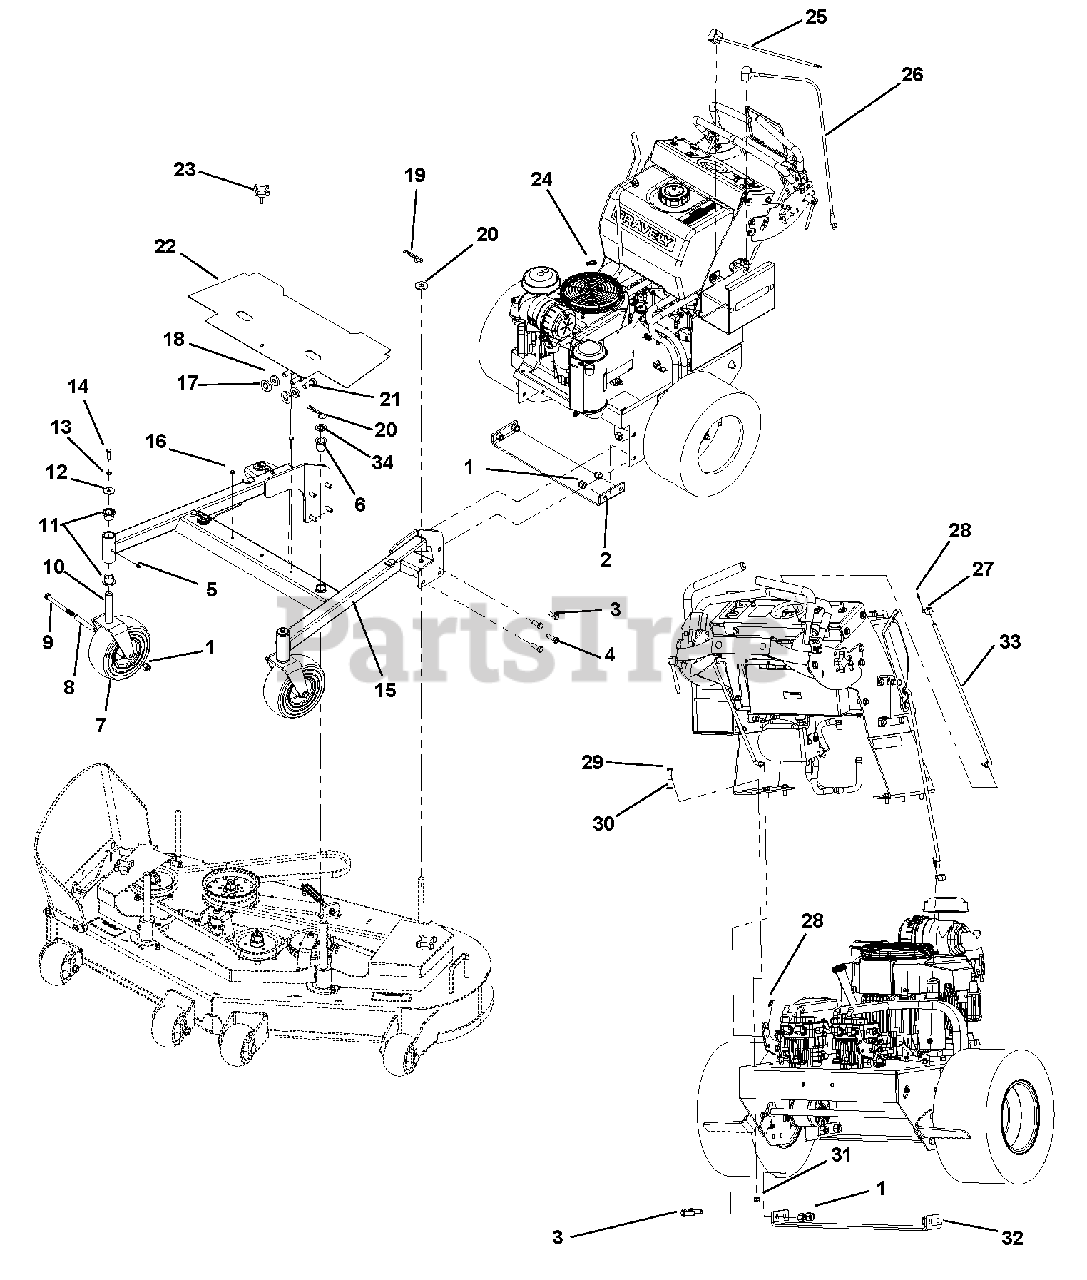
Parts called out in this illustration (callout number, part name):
1	LOCKNUT, 1/2-13 NYLOC Y
2	PLATE, ENGINE BED FRONT 48/52
3	BOLT, 1/2-13 X 1.25 HEX 5 Y
4	BOLT, 1/2-13 X 1.50 HEX 5 Y
5	FTG, 1/4-28 STRGT GREASE ZERK
6	BSHG, FLG 1.00 X 1.25 X 1.50 X 1.50 EP REV
7	ASSY, WHEEL & TIRE - 9X3.5-4
8	TUBE, CASTER AXLE
9	BOLT, 1/2-13 X 5.50 HEX 5 Y
10	WLDT, FRONT WHEEL FLOAT WALK
11	BRG, FLG 1.00X1.25X1.00
12	WSH-FL-ST .38 X 1.50 X .125 REV
13	WASHER, .375 MED SPRG LOCK Y
14	BOLT, 3/8-16 X 1.25 HEX 5 Y
15	WLDT, DECK FRAME 52 FLWLK (988148)
16	BUMPER GROMMET .125 X .25 REV
17	WASHER, .905 X 1.750X.250
18	WASHER, BLADE
19	WASHER, FLAT-STEEL .688 X 1.75 X.134 REV
20	PIN, HAIR-INTERNAL .17 X .68 X 3.50 REV B
21	BOLT, 5/8-11 X 1.50 HEX 8 Y
22	SHIELD, BELT 52 FLOAT WALK (988148)
23	KNOB, STAR 3/8-16 X 1.00
24	CABLE TIE, .15 X 8.50
25	CABLE, BATTERY GROUND 25"
26	CABLE, BATTERY - 25" POSITIVE
27	SWIVEL, 3/8-24
28	RING, RUE .375 X .054 x 1.254
29	BOLT, 3/8-16 X 1.00 HEX 5 Y
30	WASHER, .406 X .813 X .065 FLAT Y
31	LOCKNUT, 3/8-16 NYLOC Y
32	PLATE, ENGINE BED REAR
33	ROD, DRIVE CONTROL FW
34	WASHER, FLAT-STEEL REV
